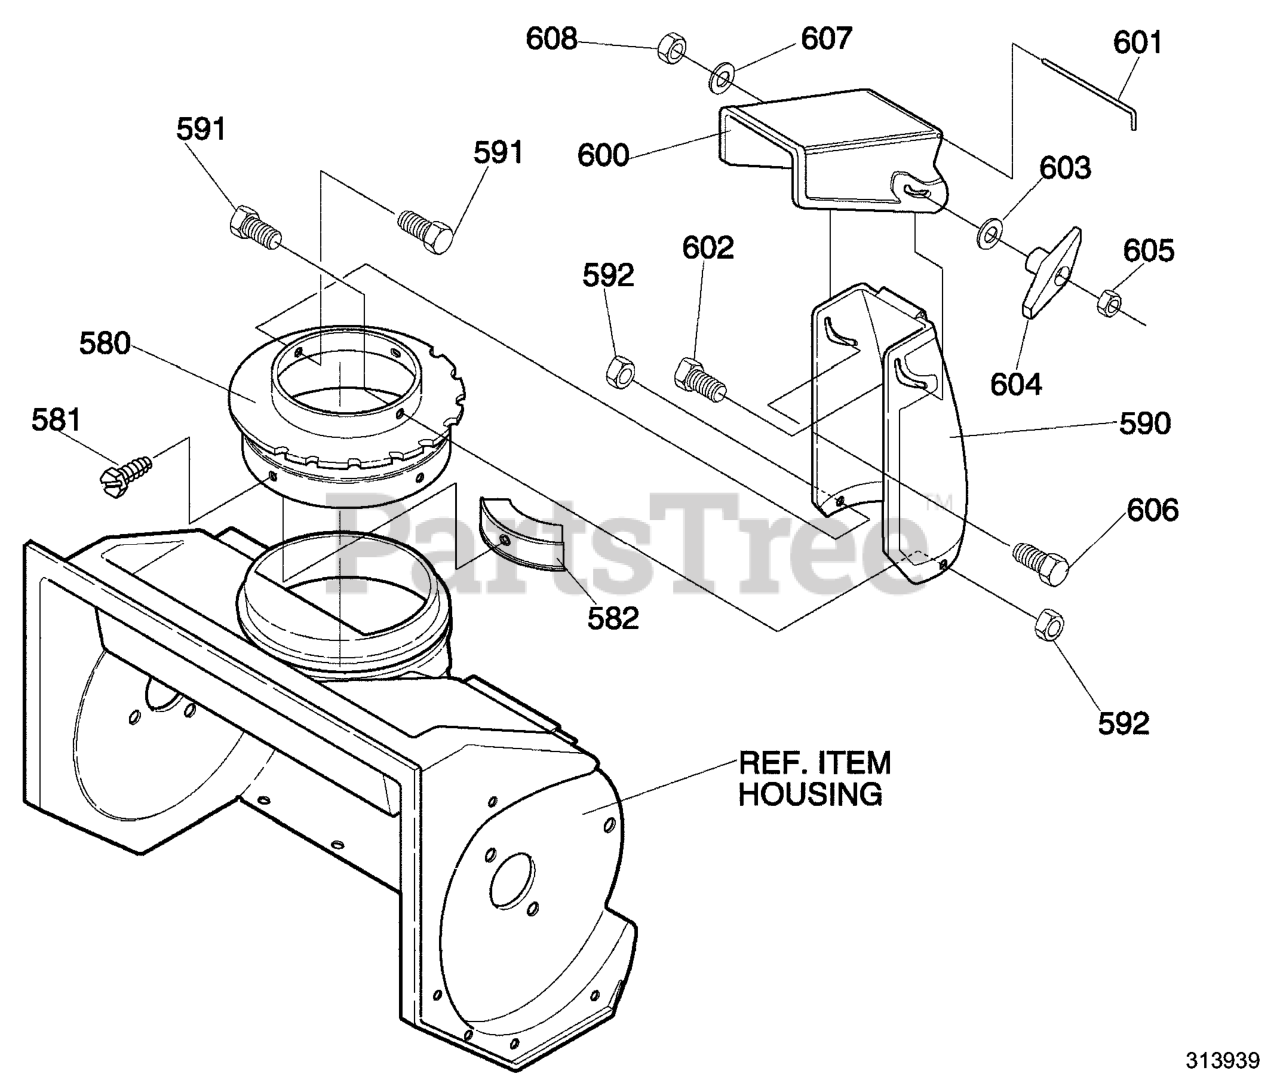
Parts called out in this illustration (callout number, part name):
580	RING, CHUTE
581	SCREW, #10X.50
582	GUIDE, CHUTE
590	CHUTE, LOWER
591	SCREW 1/4-20X.50
592	NUT, CNTRLK 1/4-2 YZ
600	CHUTE, UPPER
601	WIRE, HINGE
602	BOLT, CARRIAGE 5/16-18X1.25
603	WASHER, FLAT .349X.69X.066
604	KNOB, T
605	NUT, HEX 5/16-18
606	SCREW, 5/16-18 x 0.75
607	WASHER, FLAT .349X.69X.066
608	NUT, HEX 5/16-18
